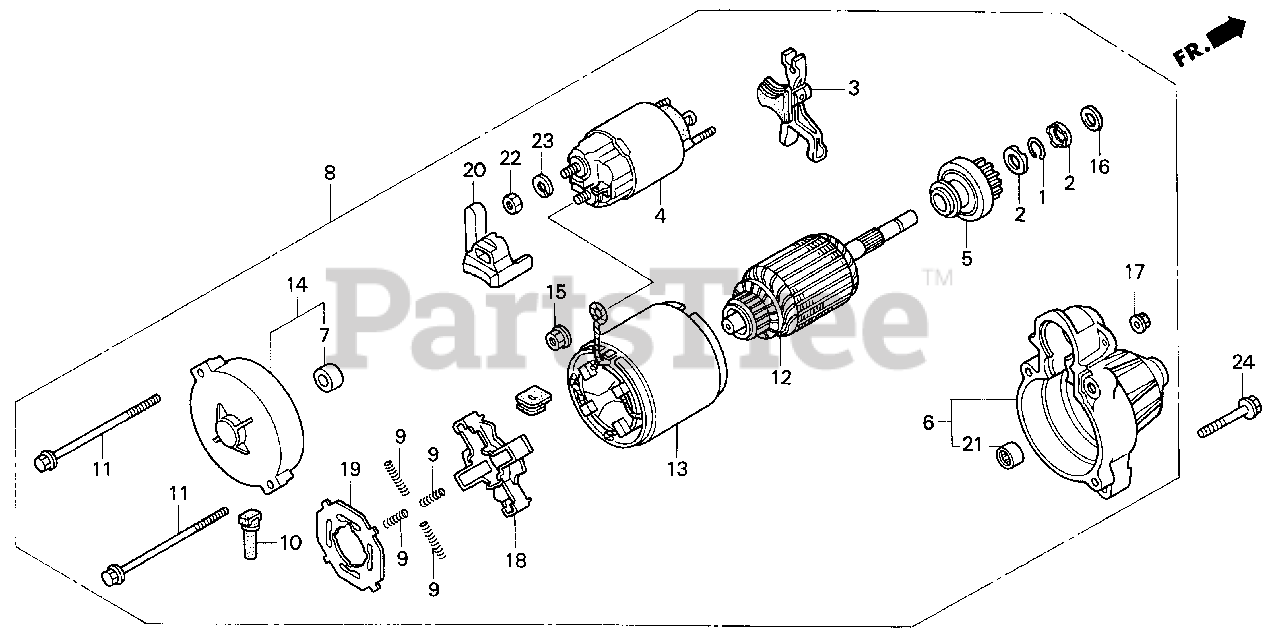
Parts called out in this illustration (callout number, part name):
1	RING, SNAP (DENSO)
2	COLLAR, CLUTCH STOP
2	COLLAR SET, CLUTCH STOP
3	LEVER, PINION DRIVE
4	SWITCH ASSY., MAGNETIC
5	CLUTCH, OVERRUNNING
6	HOUSING, SIDE DRIVE
8	MOTOR ASSY., STARTER
9	SPRING, BRUSH
10	COVER, RR.
11	BOLT, THROUGH
14	FRAME, COMMUTATOR END
15	NUT, HEX. (8MM)
17	NUT, FLANGE (5MM)
18	HOLDER, BRUSH
19	INSULATOR, BRUSH HOLDER
20	COVER, TERMINAL
22	NUT, HEX. (8MM)
23	WASHER, SPRING (8MM)
24	BOLT, FLANGE (8X40)
